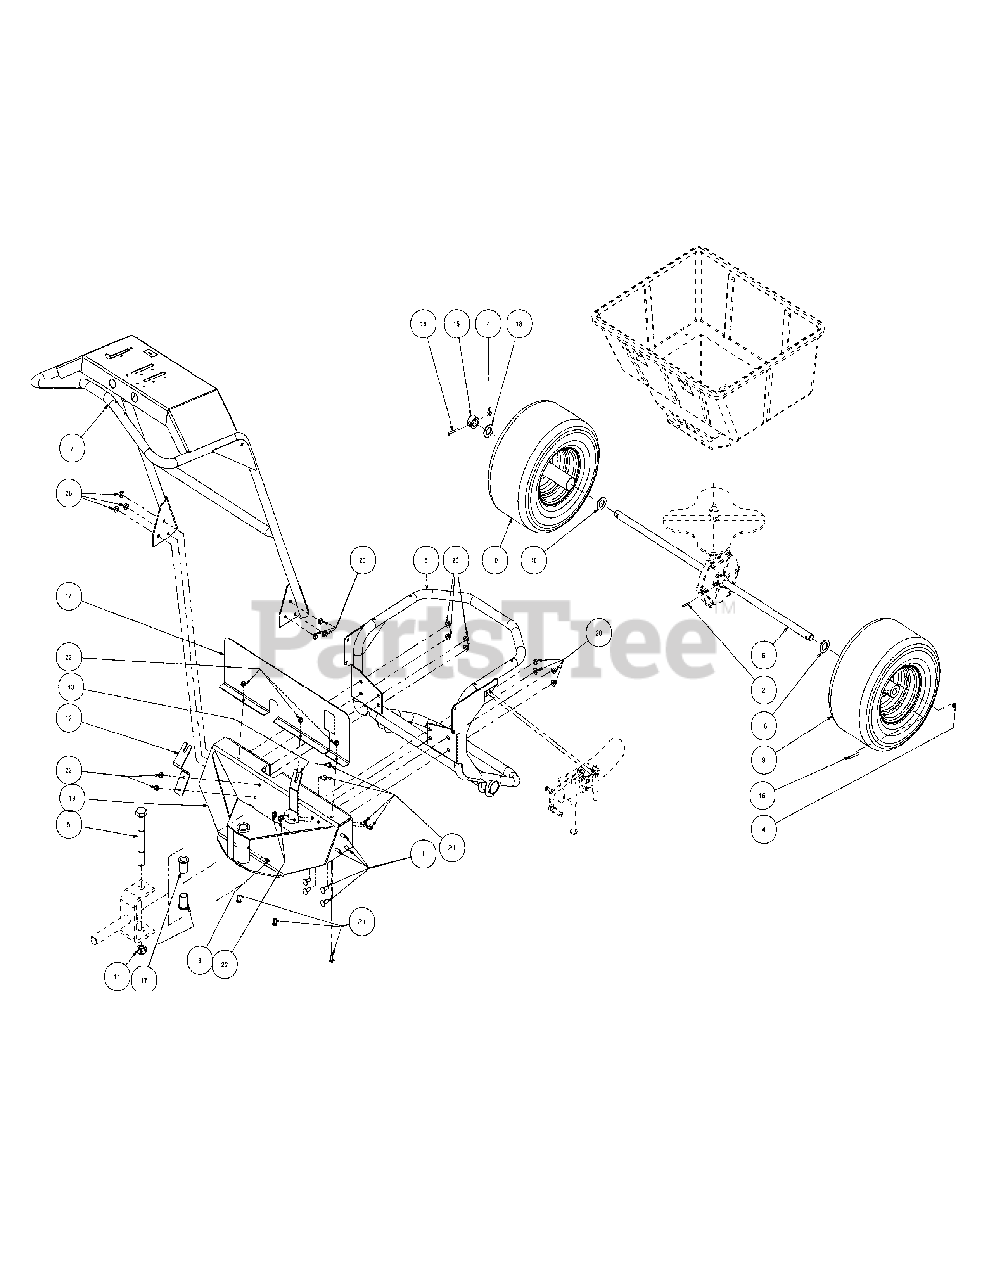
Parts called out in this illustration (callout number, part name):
1	Carriage Bolt, 5/16-18 x 3/4, SS
2	Roll Pin, 5/32 x 1-1/4, SS
3	Grease Fitting, 1/4-28 x 3/16
4	Nut, #10-24
5	Hex Cap Screw, 3/4-16 x 6.50
6	Front Axle
7	Handle Weldment
8	Front Frame bearing Assembly Includes:
8	Grease Fitting, 1/4-28 x 3/16
8	Axle Bearing
9	Drive Wheel Assmebly, 13 x 6.5-6
10	Idler Wheel Assembly, 13 x 6.5-6
11	Jam Nut, 3/4-16
12	Shut-Off Cable bracket
13	Deflector Cable bracket
14	Shield, SS
15	Shaft Collar
16	Screw, 10-24 x 1.25
18	Washer, .89ID x 1.5OD x .09, SS
19	Pivot Bracket Weldment
20	Nut, 5/16-18, Flange Whiz, SS
21	Carriage Bolt, 1/4-20 x 3/4, SS
22	Nut, 1/4-20 Flange Whiz, SS
